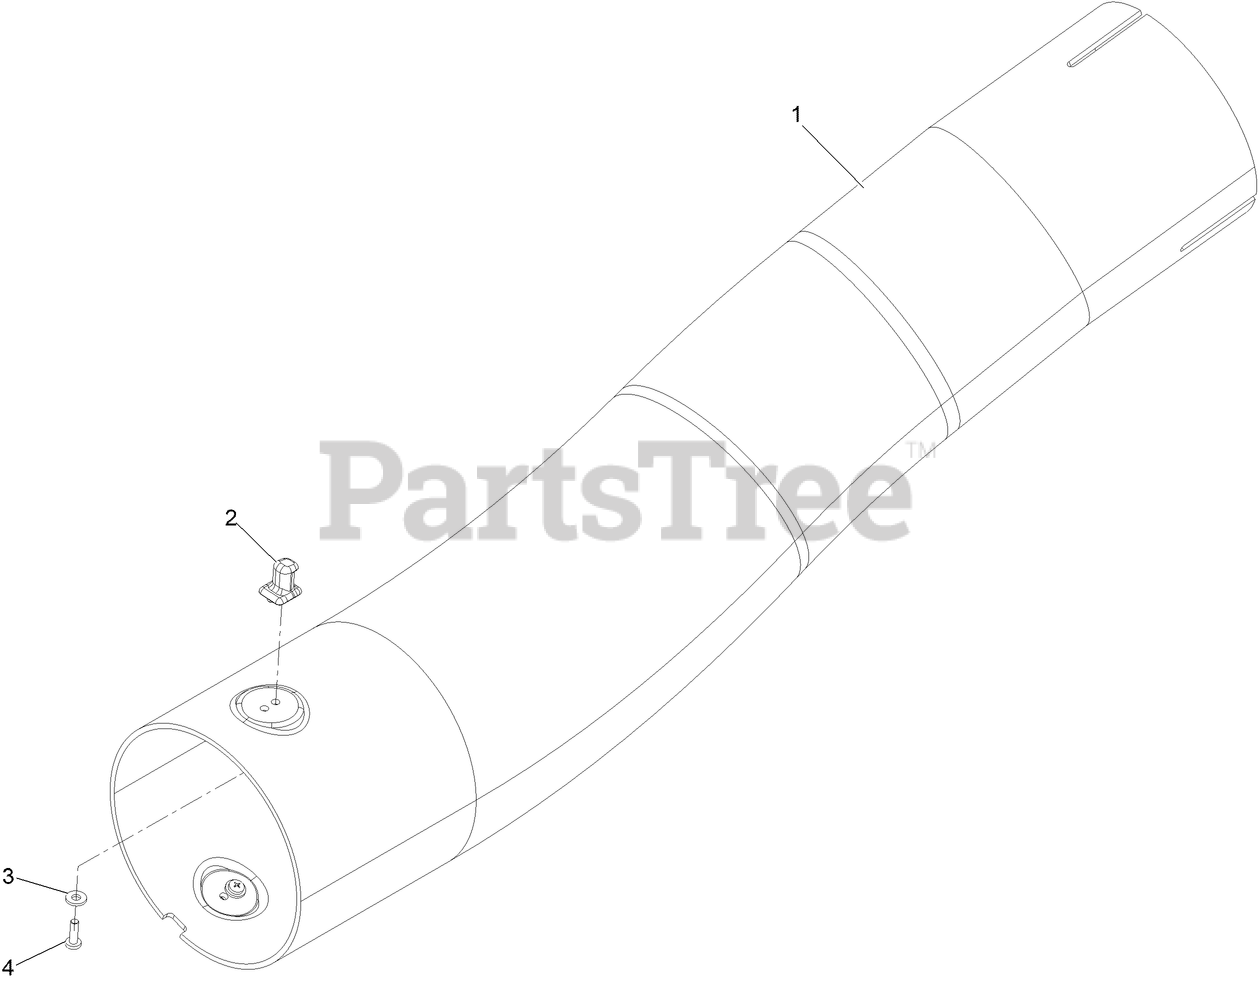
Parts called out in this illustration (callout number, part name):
2	LATCH-KEEPER
3	WASHER-FLAT
4	SCREW-PPH
